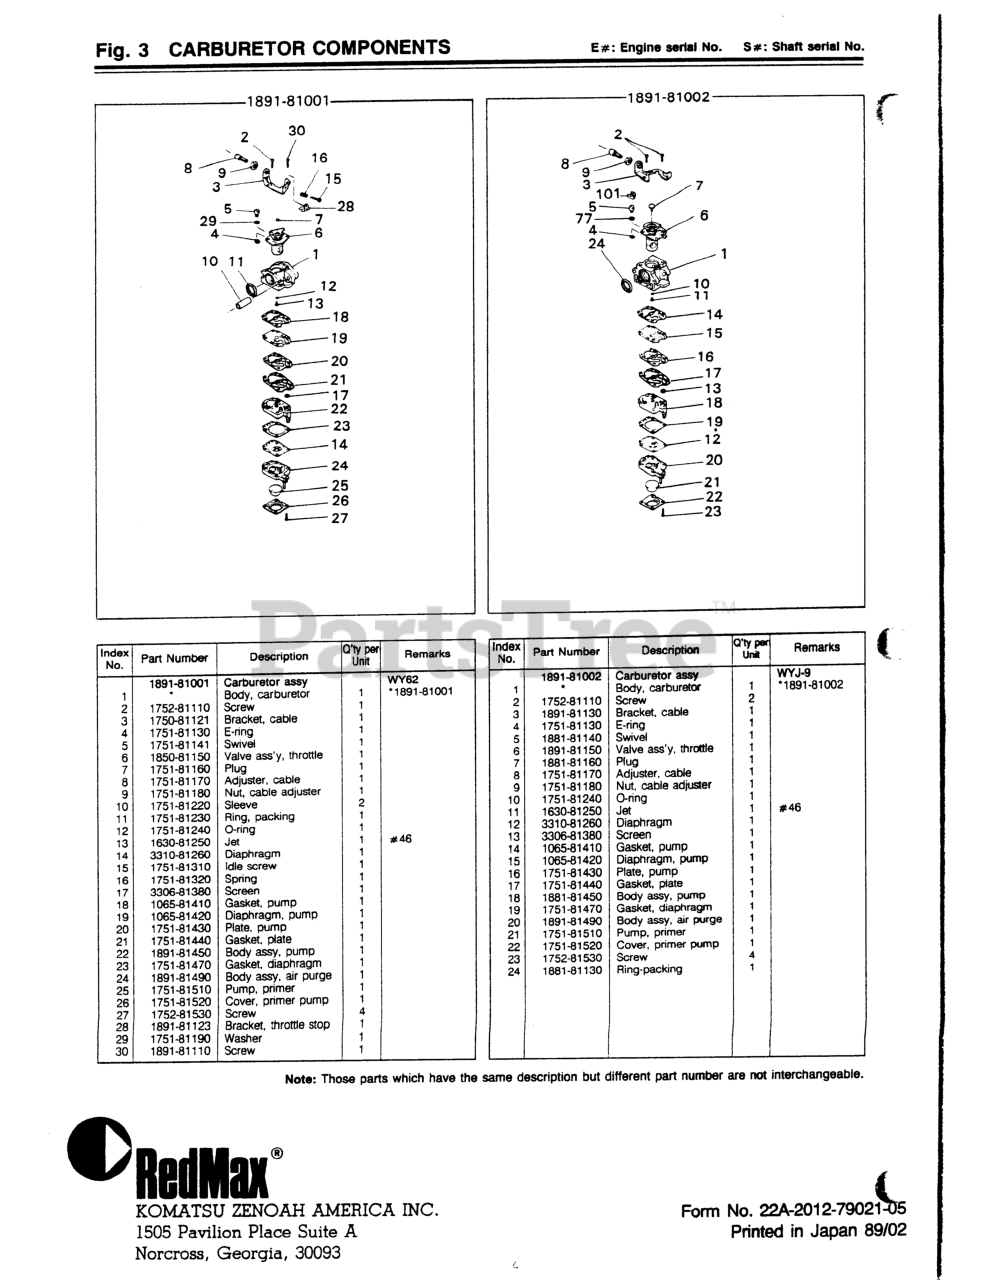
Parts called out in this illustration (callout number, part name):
1-2	SCREW
1-4	RING
1-5	SWIVEL (USE -06040)
1-6	VALVE ASSY (NO L0NGER AVAIL)
1-7	PLUG NEEDLE
1-9	NUT, CABLE ADJUSTER
1-10	SLEEVE, MOUNT
1-11	RING, PACKING (NLA)
1-12	RING, O
1-14	DIAPHRAGM (USE 4810-81260)
1-15	SCREW, IDLE AD
1-16	SPRING, IDLE A
1-18	GASKET, PUMP
1-19	DIAPHRAGM
1-20	PLATE, PUMP (NLA)
1-21	GASKET, PLATE
1-22	KIT ONLY
1-23	KIT ONLY
1-24	BODY
1-25	PUMP, PRIMING
1-26	COVER
1-27	SCREW
1-28	BRACKET (RPLS- 81122)
1-29	WASHER
2-2	SCREW
2-3	BRACKET
2-4	RING
2-5	SWIVEL
2-9	NUT, CABLE ADJUSTER
2-10	RING, O
2-14	GASKET, PUMP
2-15	DIAPHRAGM
2-16	PLATE, PUMP (NLA)
2-17	GASKET, PLATE
2-18	KIT ONLY
2-19	KIT ONLY
2-20	BODY
2-21	PUMP, PRIMING
2-22	COVER
2-23	SCREW
2-24	RING, PACKING
